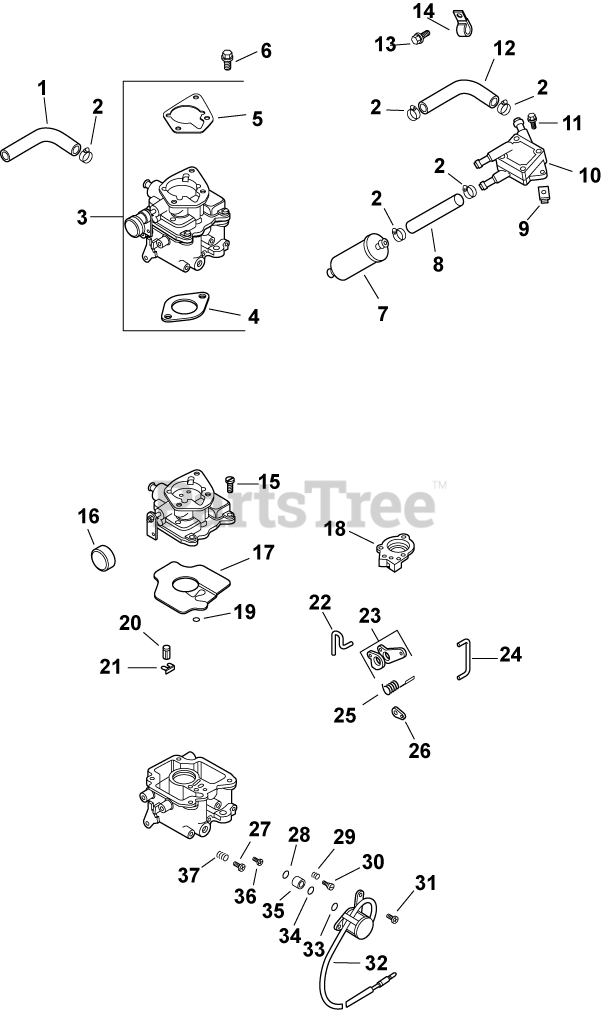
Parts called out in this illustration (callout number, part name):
1	LINE, FLEXIBLE FUEL 9.30"-USE 25 111 81-
2	CLAMP, HOSE (KM)-USE 25 237 31-S
3	KIT, CARBURETOR W/GASKET KSF
4	GASKET, CARBURETOR
5	GASKET, AIR CLEANER BASE
6	SCREW, FLG M6X1.0X30
7	FILTER, FUEL (9-12 MICRON)-USE 24 050 13
8	LINE FLEXBLE FUEL (3.5" x.25") -USE 25 1
9	NUT, PLASTIC (KM)-USE 25 100 37-S
10	PUMP, FUEL
11	SCREW, TAP M6X1.7X18
12	LINE, FLEXIBLE FUEL 15 1/2"
13	SCREW, FLG M6X1.0X12
14	CLIP, CABLE
15	SCREW, CARBURETOR BODY
16	CAP, CHOKE LEVER
17	GASKET, CARBURETOR BODY
18	HOUSING, PUMP
19	O-RING, SLOW JET
20	VALVE, INLET NEEDLE
21	CLIP, INLET NEEDLE VALVE
22	LINKAGE, ROD
23	LEVER, LINK
24	LINKAGE, ROD
26	LEVER, LINK
27	JET, MAIN
28	O-RING, SOLENOID
29	SPRING, IDLE NEEDLE
30	NEEDLE, IDLE
31	SCREW, SOLENOID
32	SOLENOID ASSEMBLY
33	O-RING, SOLENOID
34	O-RING, SOLENOID
35	SEAT, SOLENOID
36	SCREW, IDLE
37	SPRING, IDLE SPEED ADJ SCREW
